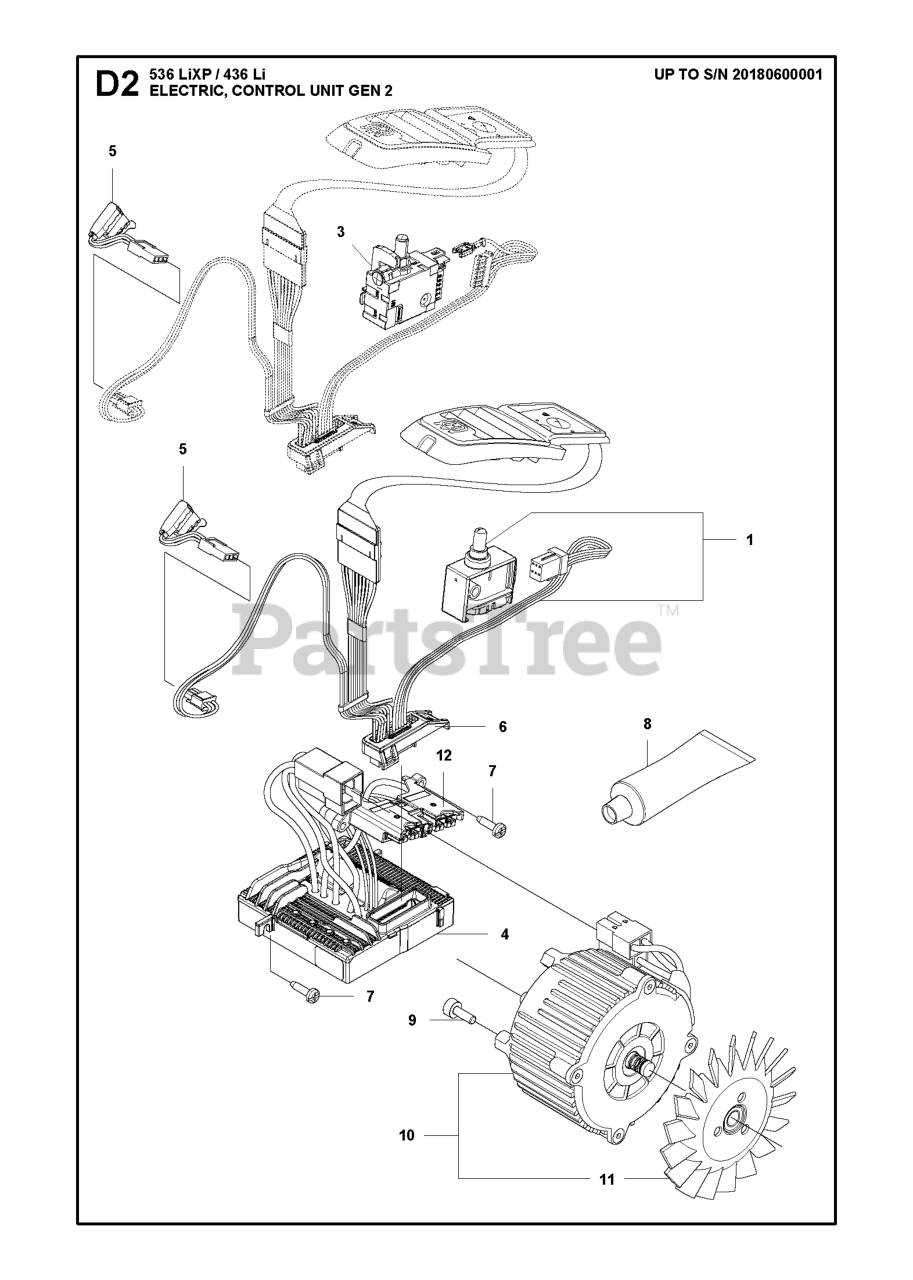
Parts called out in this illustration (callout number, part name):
1	SWITCH KIT BATTERY REAR HANDLE
3	TRIGGER SWITCH
4	CONTROL UNIT
5	WIRING ASSY
8	GREASE TUBE Q8 RUYSDAEL WR2
10	MOTOR ASSY BLDC D70
12	CONNECTOR BATTERY
